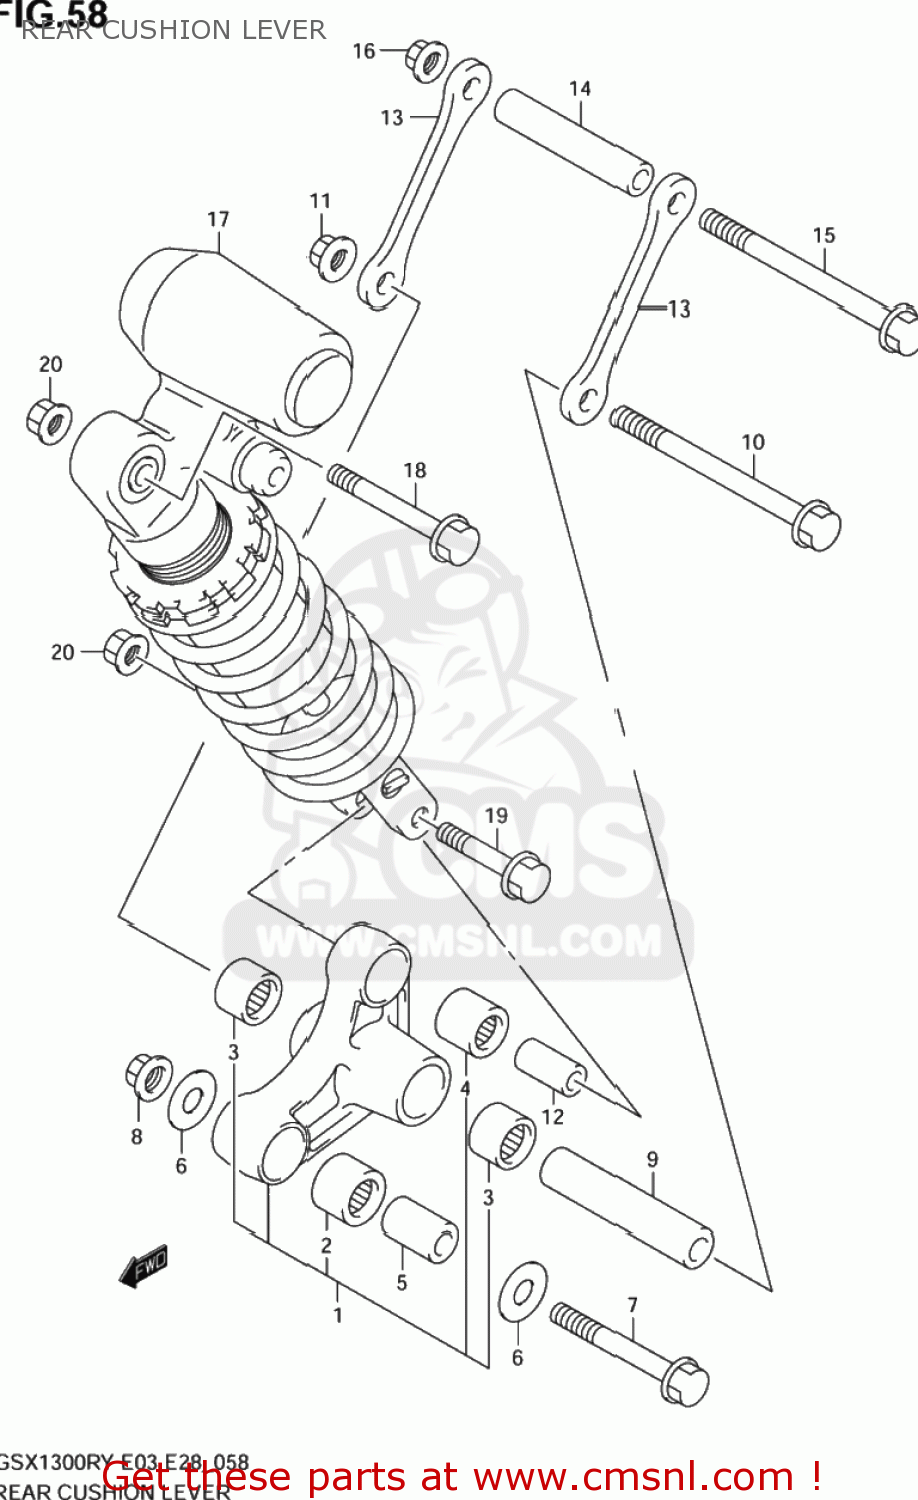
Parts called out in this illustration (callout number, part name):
1	LEVER SET,RR CUSHION
2	BEARING(20X27X30)
3	BEARING(20X27X23.5)
4	BEARING(17X24X26)
5	SPACER,RR CUSHION LEVER FR
6	WASHER
7	BOLT,RR CUSHION LEVER FR
8	NUT 12MM
9	SPACER,RR CUSHION LEVER CTR
10	BOLT,RR CUSHION LEVER CTR
11	NUT 12MM
12	SPACER,RR CUSHION LEVER
13	ROD,RR CUSHION
14	SPACER,RR CUSHION LEVER CTR
15	BOLT,RR CUSHION LEVER CTR
16	NUT 12MM
17	ABSORBER ASSY,RR SHOCK
18	BOLT(10X70)
19	BOLT(10X58)
20	NUT
